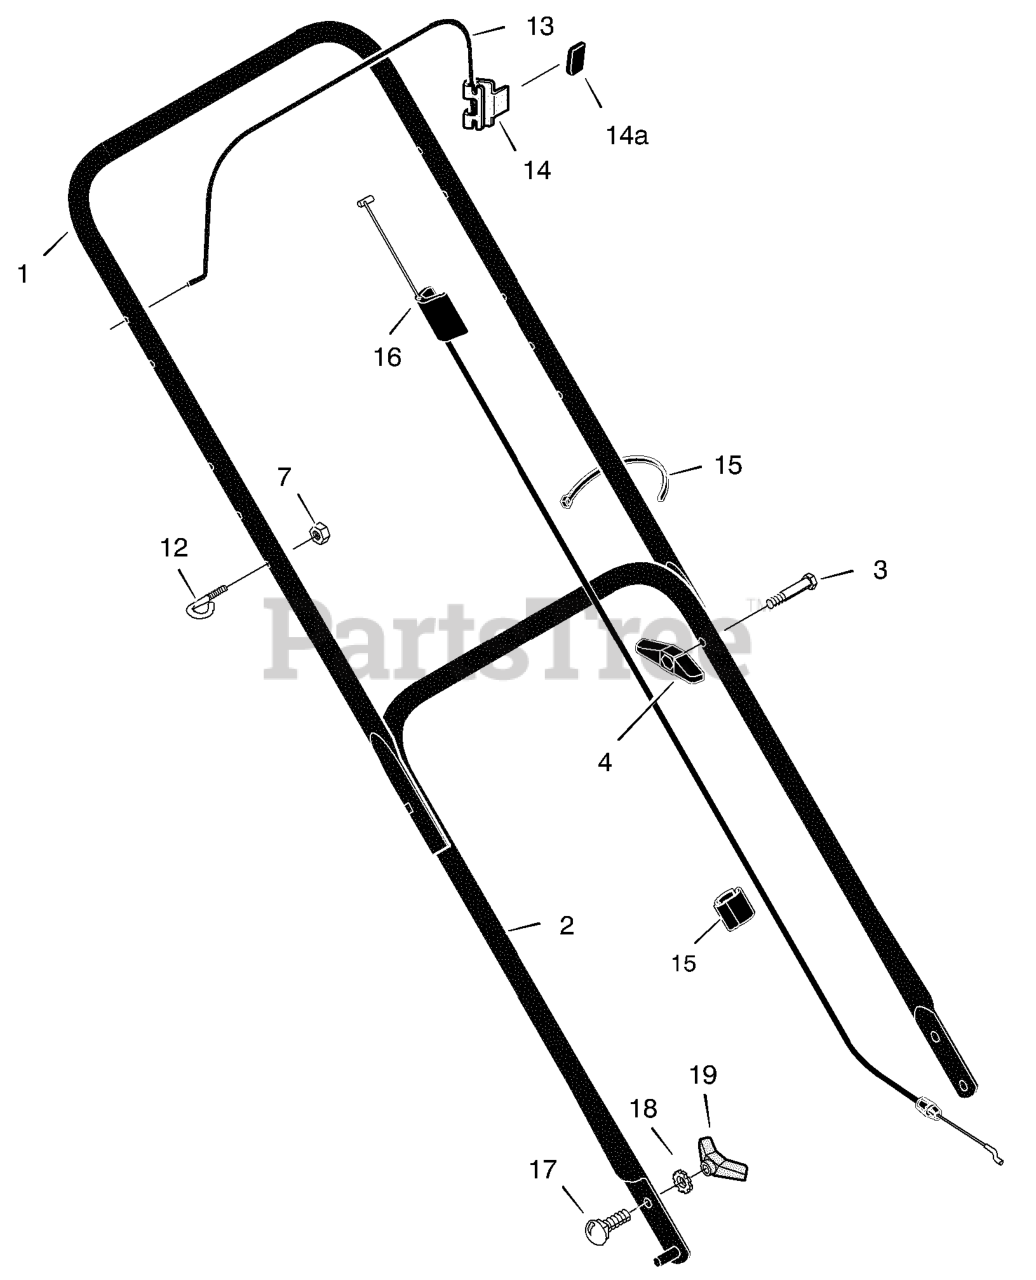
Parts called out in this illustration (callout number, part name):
1	Handle, Upper (Black)
2	Handle, Lower (Black)
4	Knob, Plastic
7	Locknut
12	Guide, Rope
13	Engine Stop Lever
14	Bracket, Stop Lever
15	Fastener, Cable
16	Engine Stop Cable
17	Bolt, Carriage
19	Knob, Plastic
